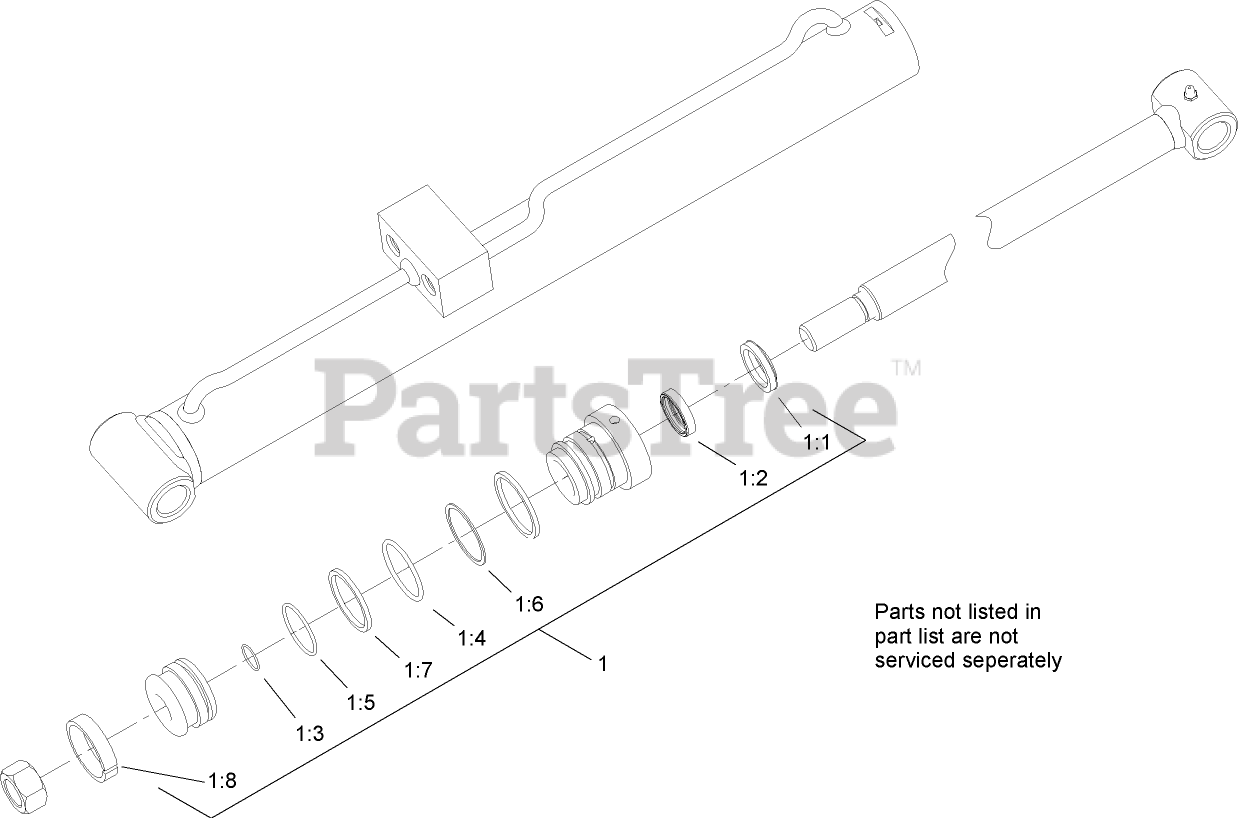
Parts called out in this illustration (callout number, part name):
1	SEAL KIT
1:1	Wiper
1:2	Seal ASM
1:3	Seal-Dust
1:4	Seal-Dust
1:5	Seal-Dust
1:6	Back-up
1:7	Seal ASM
1:8	RING-WEAR
